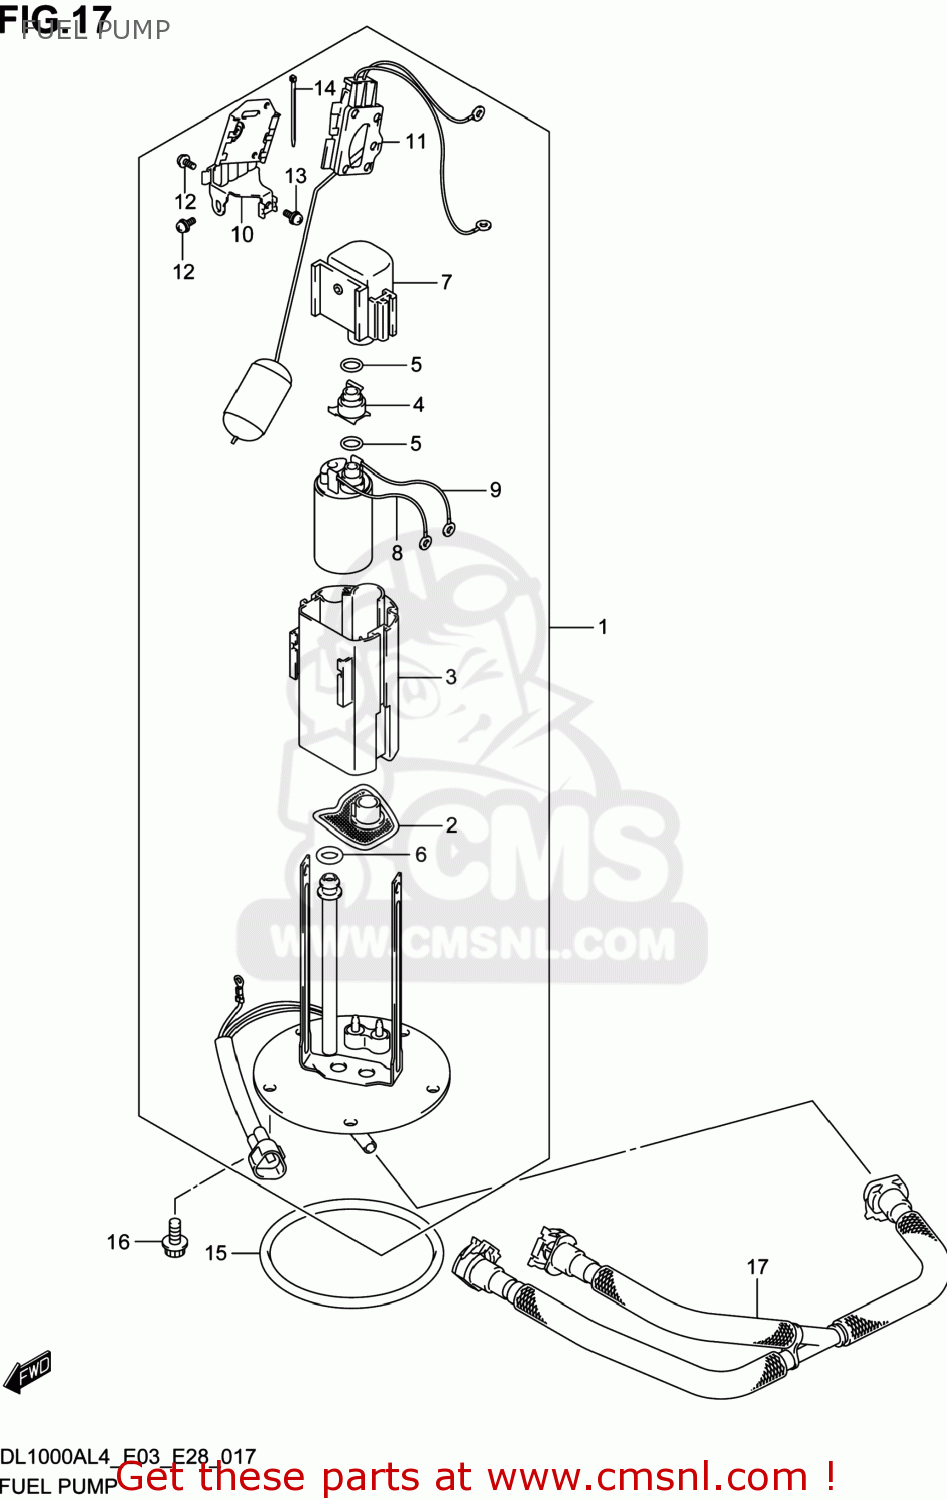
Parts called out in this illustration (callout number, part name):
1	PUMP ASSY,FUEL
2	STRAINER
3	CUP
4	JOINT
5	O RING
6	O RING
7	REGULATOR,FUEL
8	WIRE,EARTH
9	WIRE,LEAD
10	BRACKET,FUEL GAUGE
11	GAUGE ASSY
12	SCREW
13	SCREW
14	BINDER
15	O RING,FUEL PUMP
16	BOLT
17	HOSE,FUEL
